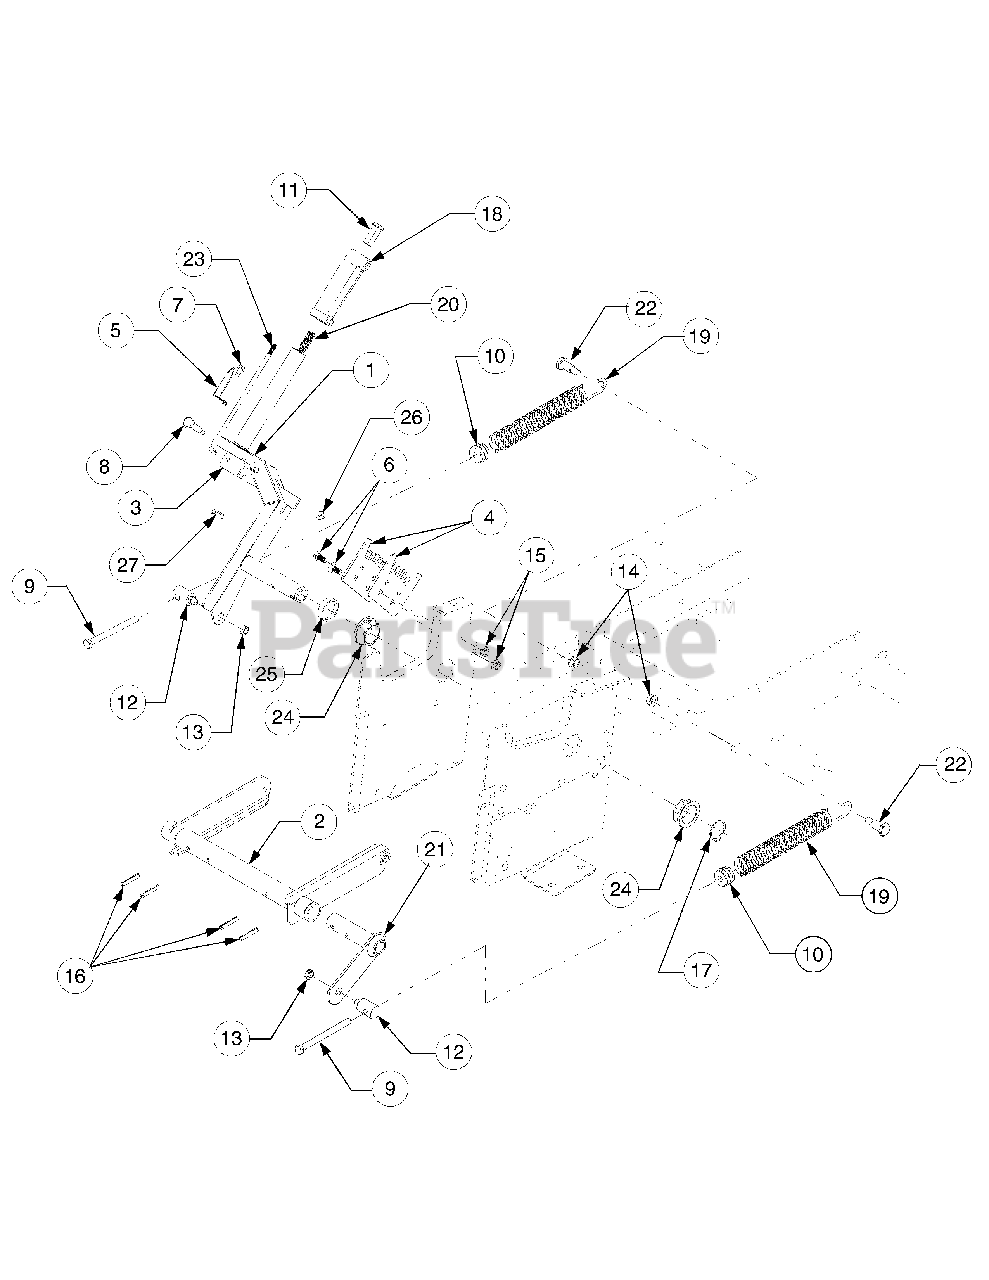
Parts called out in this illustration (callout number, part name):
2	Shaft Assembly, Lift
5	Indicator, Lift Height
6	Bolt, Carriage, 5/16-18 x .75
7	Screw, Hex Wash Tapp, 1/4 x .5
8	Screw, Shoulder, .374 x 1.375
9	Screw, Hex Cap, 3/8-16 x 4.25 GR5
10	Insert, Spring
11	Button, Handle
12	Ferrule, Adjustment
13	Nut, Hex Center Lock, Jam, 3/8-24
14	Nut, Hex Flanged Lock, 3/8-16
15	Nut, Hex Flanged Top Lock, 5/16-18
16	Pin, Spiral Spring, 1/4 Dia x 1.5
17	Ring, Snap, 1.25 Dia Shaft
18	Grip, Lift Handle
19	Spring, Extension
20	Spring, Compression
22	Bolt, Shoulder
23	Rod, Index
24	Bearing, Hex Flange, 1.25 ID
25	Spacer, 1.28 ID x 1.5 OD x .335 Lg
26	Nut, Hex Flange Lock, 1/4-20
27	Pin, Internal Cotter
